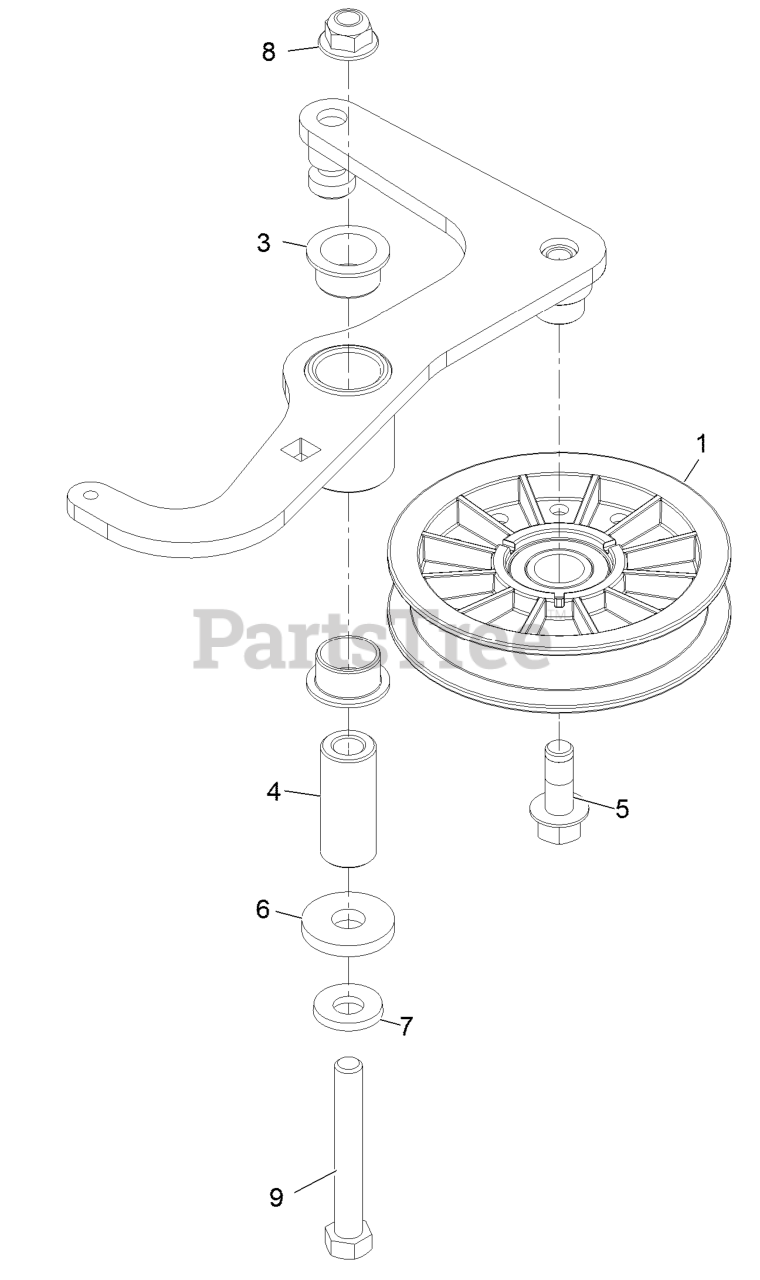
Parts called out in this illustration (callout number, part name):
1	PULLEY-IDLER, FLAT
3	BUSHING-FLANGE
4	SPACER, PIVOT
5	SCREW-HFH
7	WASHER-BELLEVILLE
8	NUT-HF, NI
9	SCREW-TAP
